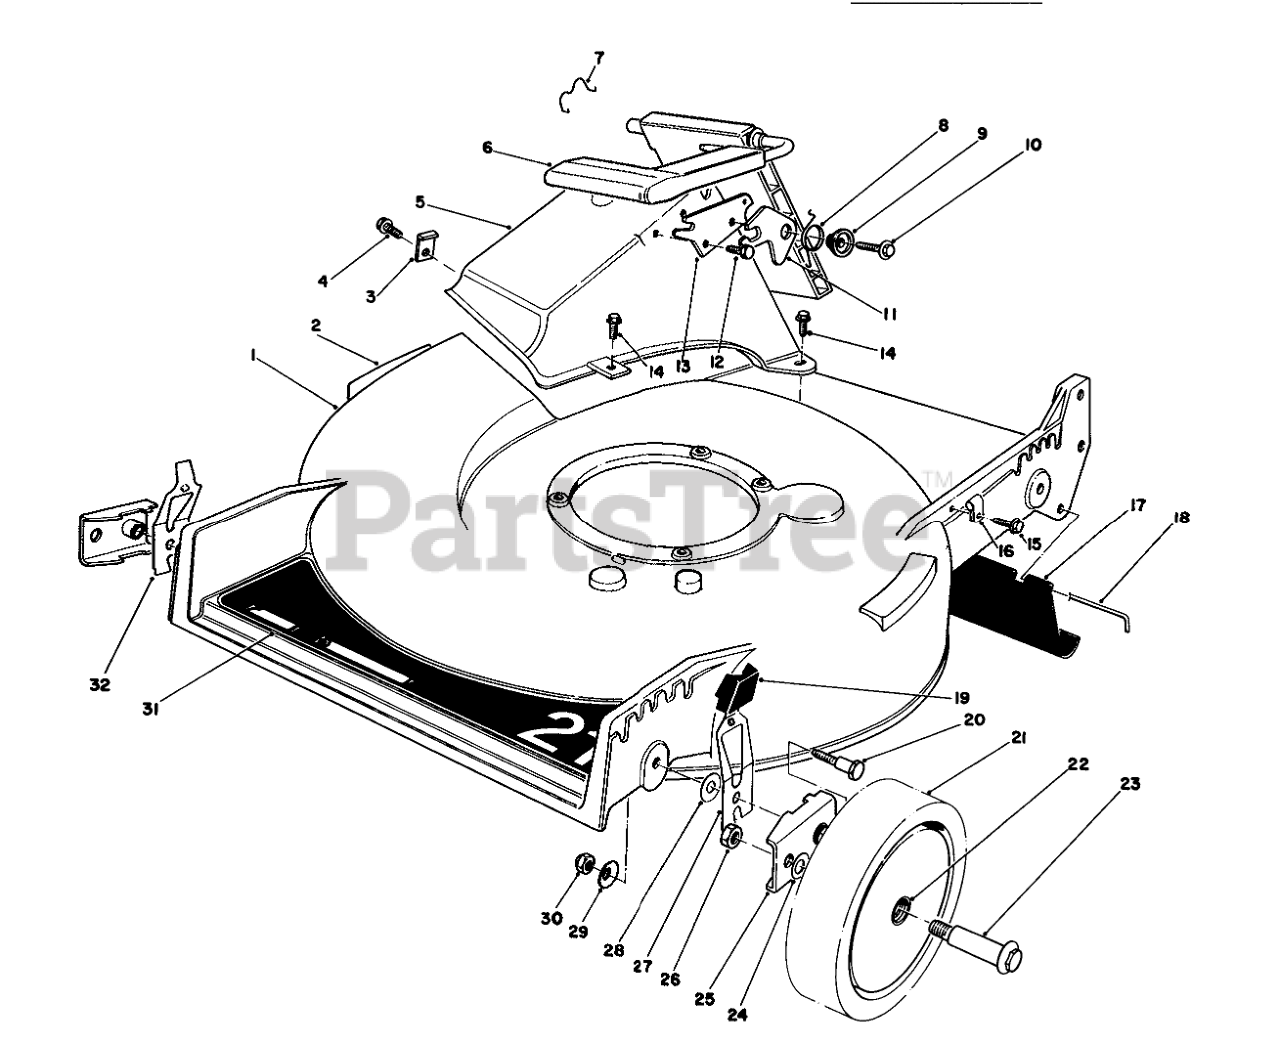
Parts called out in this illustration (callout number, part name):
1	Housing (Incl. Ref. #2)
2	DECAL-DANGER
3	TUNNEL CLIP
4	SCREW
5	Tunnel Discharge
6	Discharge Door Assembly
7	DOOR RET SPRING
8	TORSION SPRING
9	DOOR SPACER
10	SCREW-HWH
11	SAFETY LATCH
12	SCREW-PLASTITE
13	DOOR LATCH PLATE
14	SCREW-HWH
15	SCREW
16	CLAMP-CABLE
17	SHIELD-TRAILING
18	ROD-SHIELD
19	KNOB-ARM
20	PIVOT SCREW
21	Wheel & Tire Assembly (Incl. Ref. #22)
22	BUSHING
23	BOLT-WHEEL
24	WASHER
25	HP PIVOT ARM ASM
26	Nut
27	L. HP SPRING ARM ASM
28	WASHER-PIVOT
29	WASHER-BELLEVILLE
30	NUT-LOCK, NI
31	DECK DECAL
32	R HP SPRING ARM ASM
